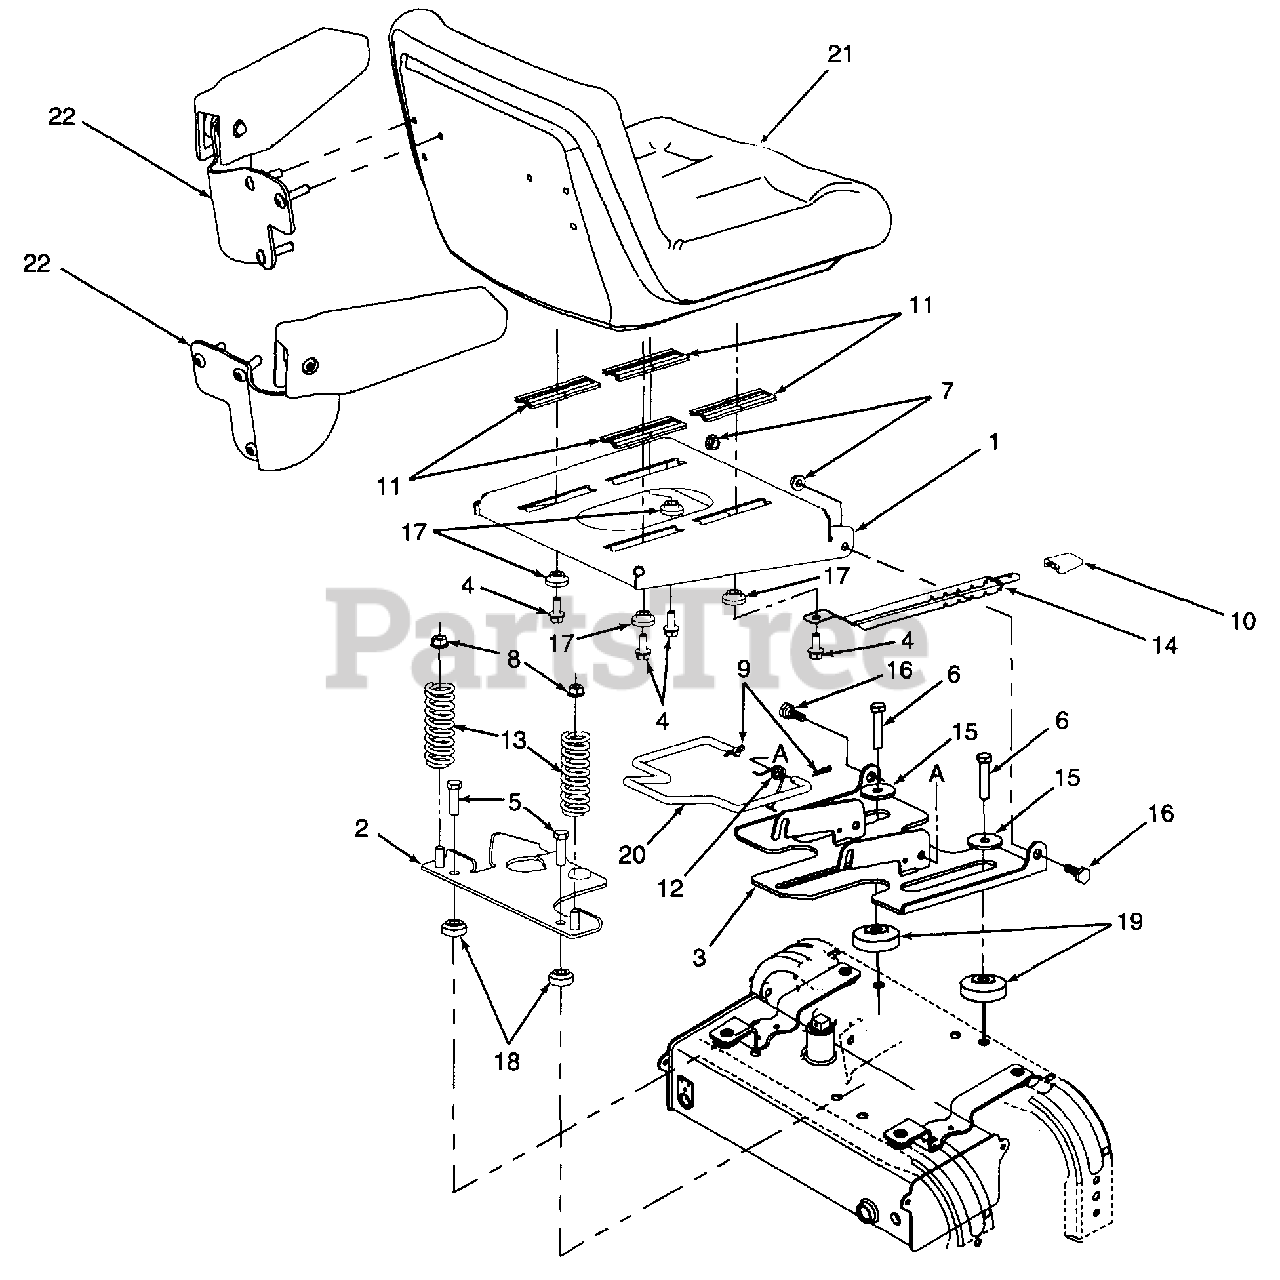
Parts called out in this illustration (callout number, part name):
1	Seat Base
4	Screw, Hex Wash Hd Tapp 5/16-18 x .75
5	Screw, Hex Cap 3/8-16 x 1.5 GR5
6	Screw, Hex Cap 3/8-16 x 1-3/4 GR5
7	Nut, Hex Flange Lock 5/16-18 GR5
8	Nut, Hex Flange Lock 3/8-16 GR5
9	Pin, Internal Cotter
10	Knob, Seat Adjustment
11	Seat Slide
12	Spring, Torsion
13	Spring, Compression
14	Spring, Index
15	Washer, Flat, .390 x 1.5 x .134
16	Bolt, Shoulder .437 x .268:5/16-18
17	Spacer, Shoulder, .38 I.D.
18	Spacer, Shoulder
19	Spacer, Seat Pan Shoulder
20	Rod, Seat Pan Lock
21	Seat Assembly
22	Seat Arm
